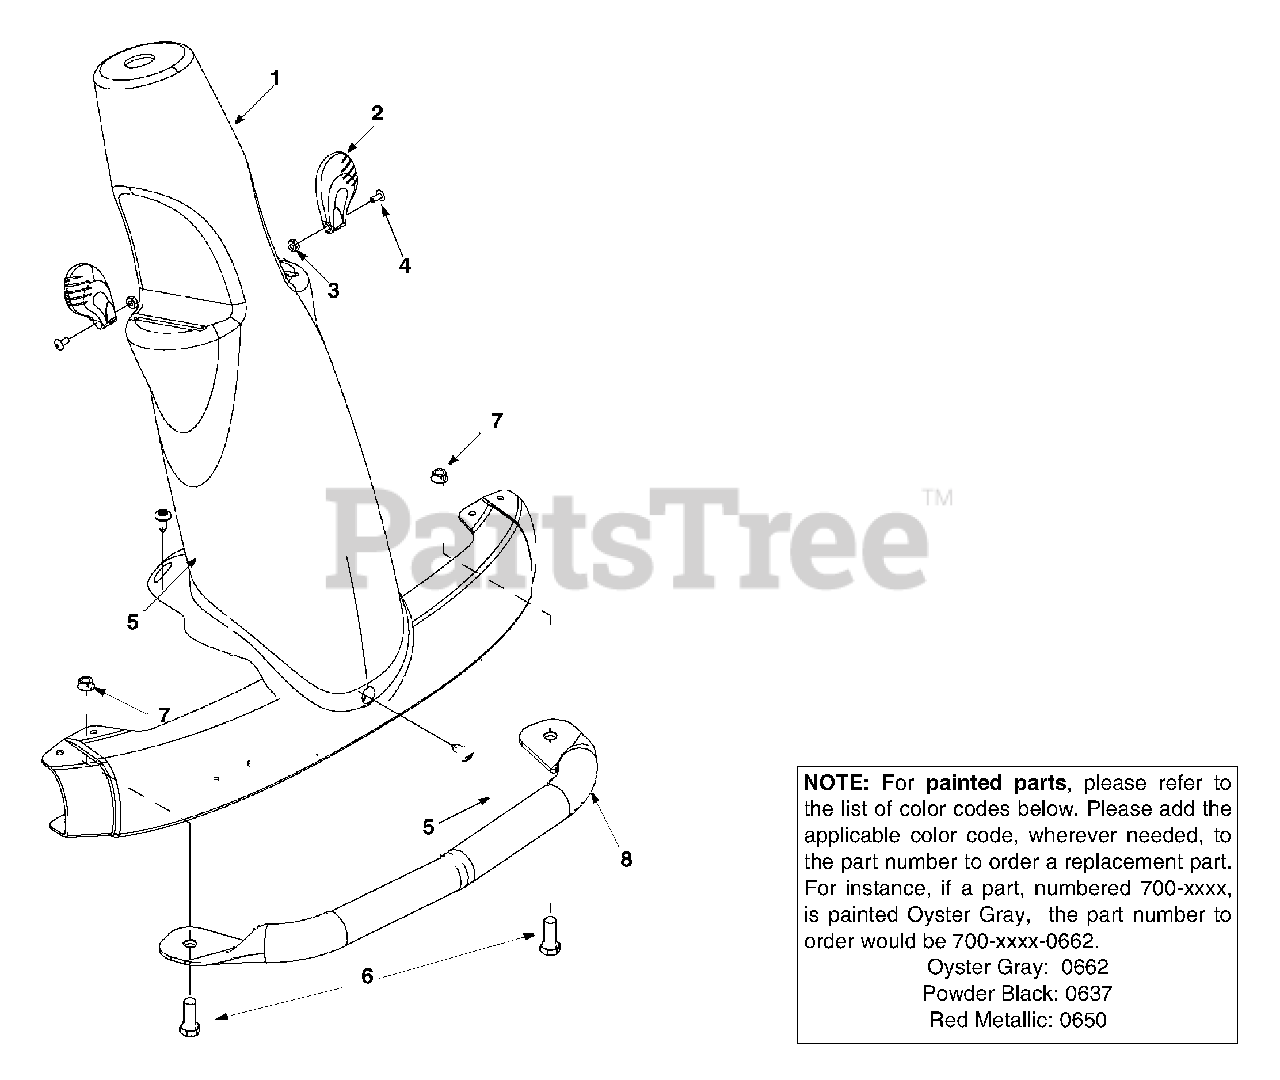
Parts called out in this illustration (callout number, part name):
1	Steering Column: Black
2	Control Knob
3	Hex Nut 8-32
4	Pan Head Machine Screw #8-32
5	Hex Screw TT 1/4-20 x .50"
6	Hex Screw 3/8-16 x 1.0"
7	Lock Nut
